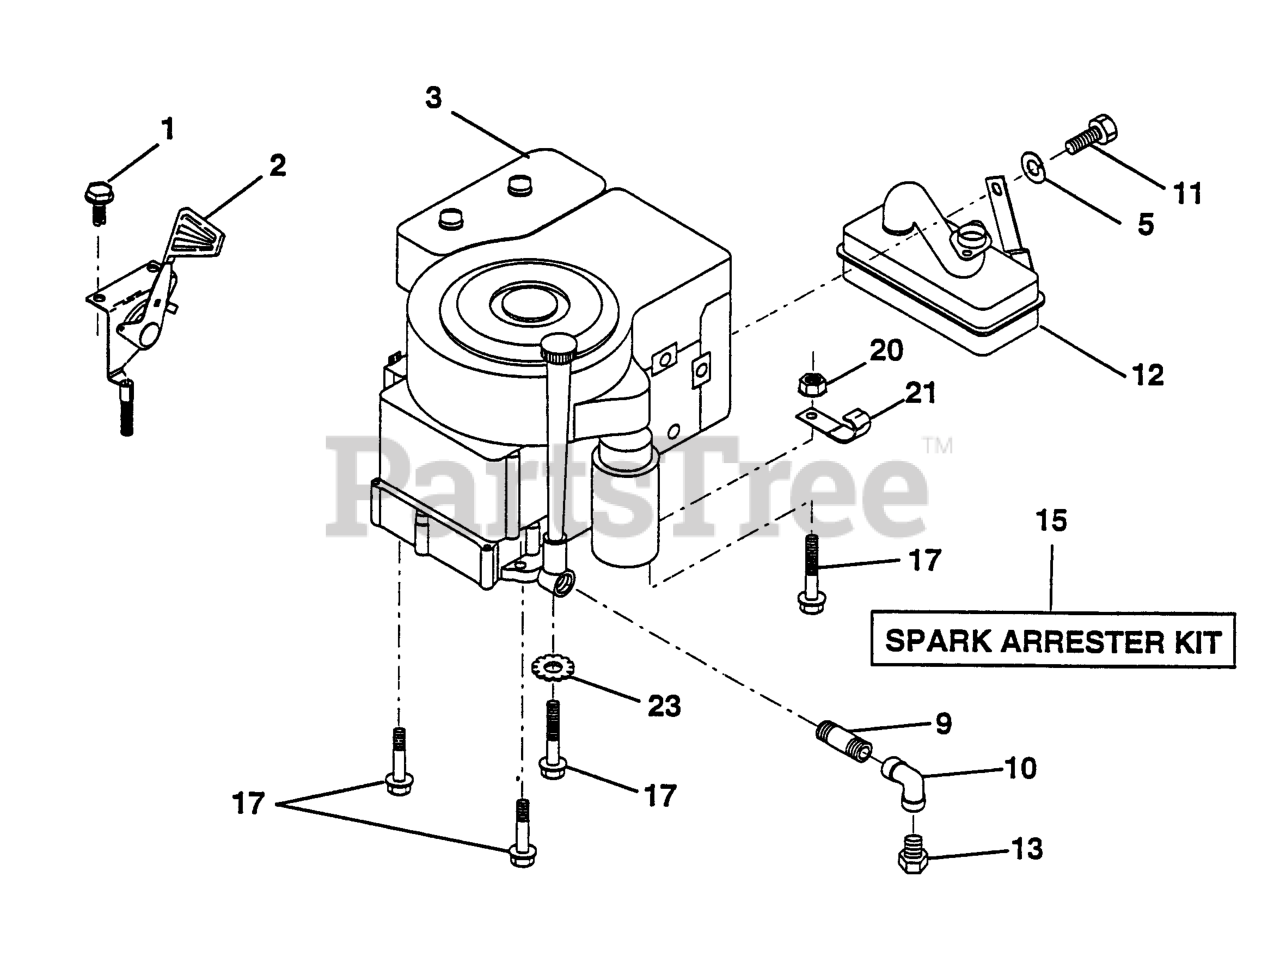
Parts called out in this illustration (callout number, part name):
2	CONTROL.TH/CH.RH.BLK.FLG.26
3	Engine, Kohler, 12.5 HP, Model
5	WASHER.LOCK.HVY.HLCL.SPR.5/16
9	Nipple Pipe
10	ELBOW
11	Bolt, Hex, Fin. 5/16 -18 x 1/2
12	MUFFLER KOH
13	Oil Drain Plug
15	KIT.SPARK ARRESTOR 794945 B&S
17	BOLT, HEX
21	CLIP T
23	LOCKWASHER
